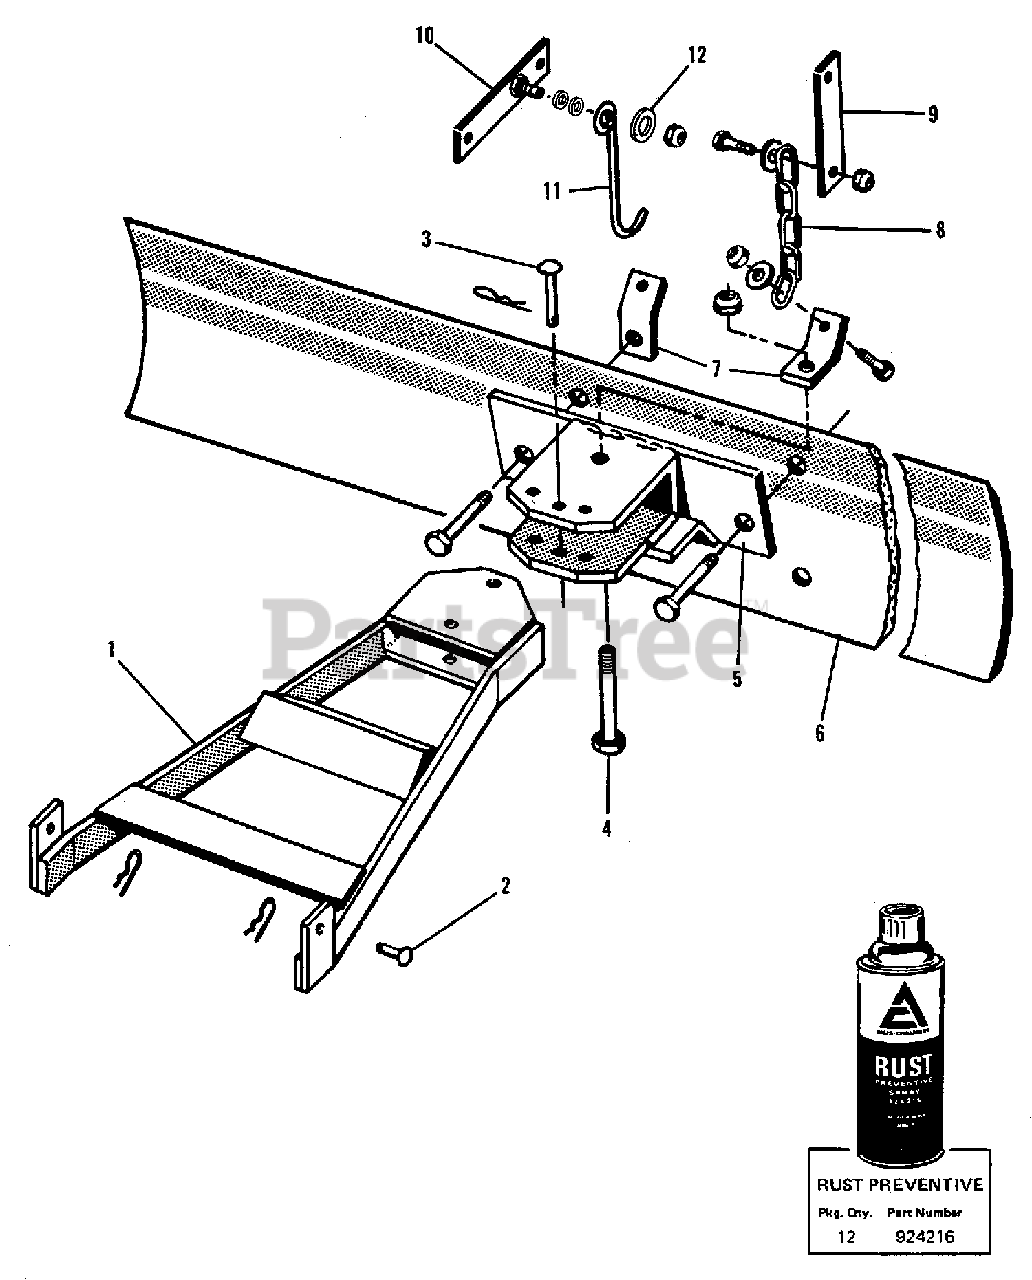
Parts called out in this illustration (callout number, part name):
1	DRAWBAR ASSEMBLY, Grader
2	PIN, Round Head
2	PIN, Quick
3	PIN, King
3	PIN, Quick
4	CAPSCREW, 5/8NC x 3
4	NUT, 5/8NC, Lock
5	HITCH ASSEMBLY, Grader
5	CAPSCREW, 5/8NC x 2
5	LOCKWASHER, 5/8
5	NUT, 5/8NC
6	BLADE, 42" Grader
7	LINK, Lift
8	CHAIN ASSEMBLY, Lift
8	CAPSCREW, 3/8NC x 1
8	WASHER, 3/8, Plain
8	NUT, 3/8NC, Lock
9	BRACKET, Lift
10	BRACKET ASSEMBLY, Transport
10	CAPSCREW, 5/16NC x 3/4
10	NUT, 5/16NC
10	LOCKWASHER, 5/16
10	WASHER, 5/16, Plain
10	NUT, 5/16NC, Lock
11	HOOK, Transport
12	WASHER, Special Nylon
